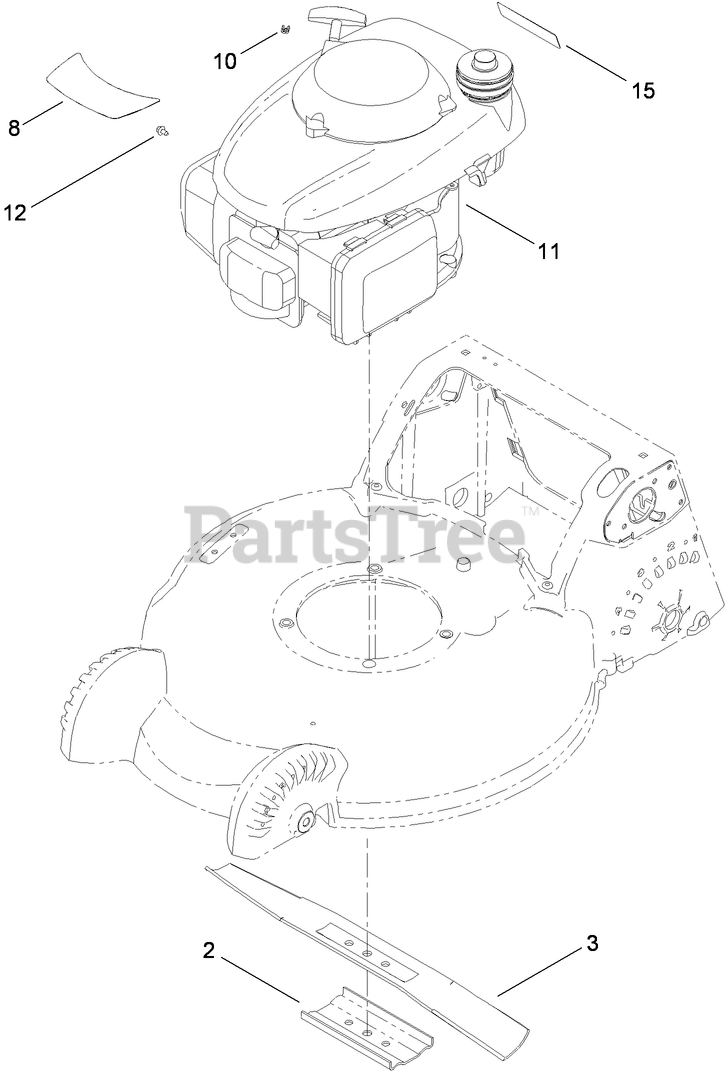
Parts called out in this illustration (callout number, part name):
2	SUPPORT-BLADE
3	BLADE-BAGGING
8	DECAL-ENGINE
10	STOP-ROPE
12	SCREW-HWH
15	DECAL-ARRESTER, SPARK
